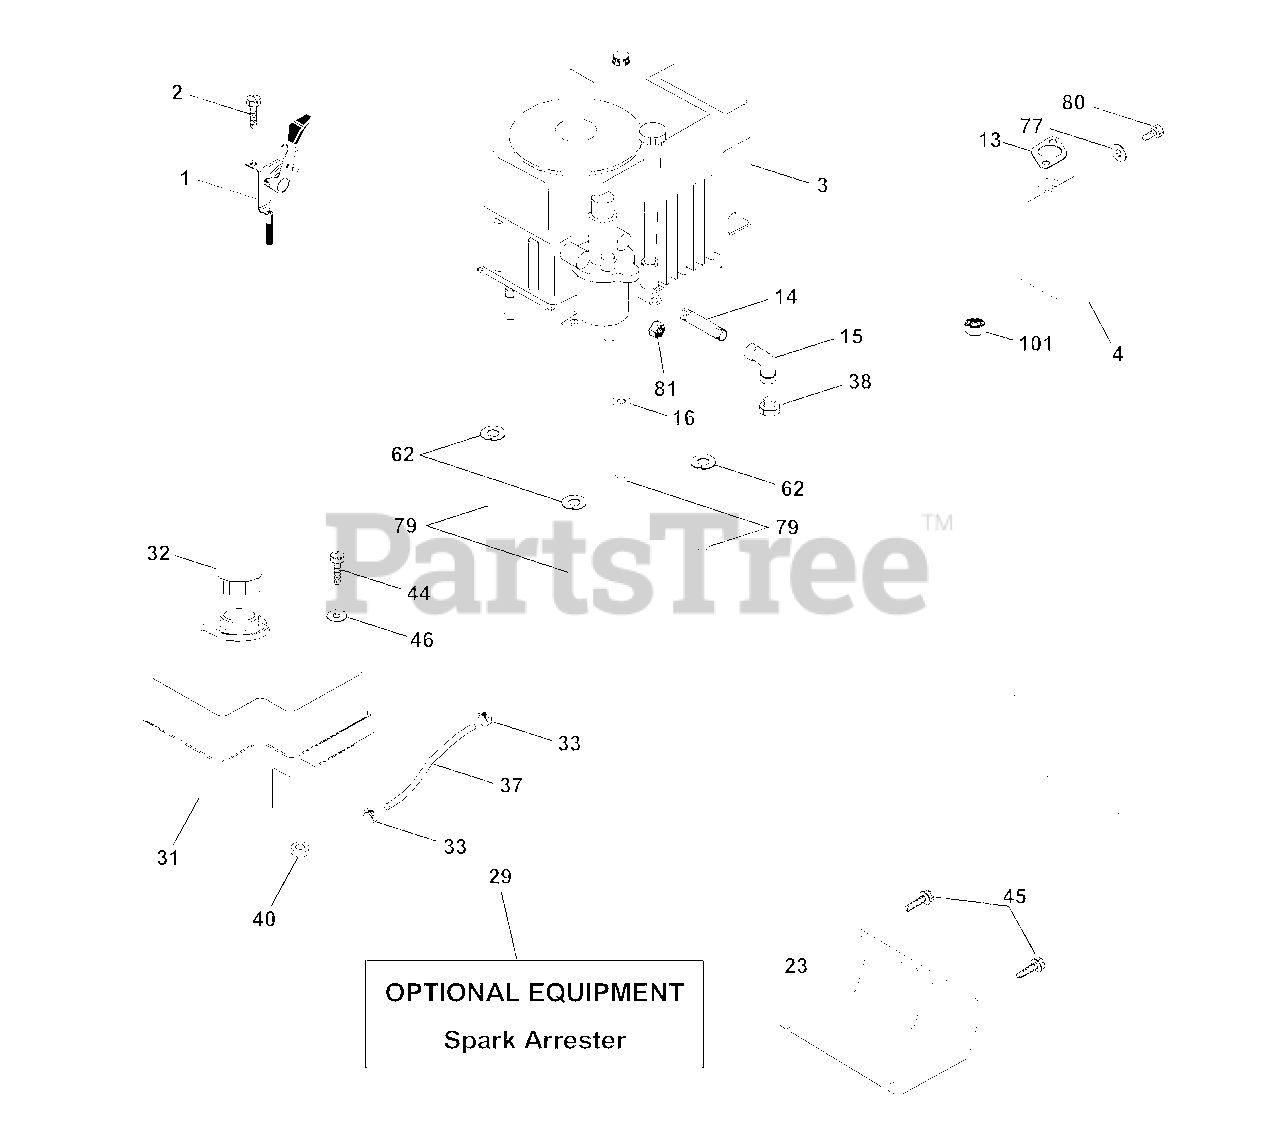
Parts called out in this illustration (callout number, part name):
1	Control Th/ch 27 LH Flag
2	Screw Hex Thd Cut 1/4-20x5/8 T
4	Muffler
14	Nipple Pipe
15	Elbow Std 90 Degree 3/8-18 Npt
16	Washer Lock Ext Tooth 5/16
23	Shield Brn/Dbr Guard
29	Kit Spark Arrestor (Flat Scrn)
31	Tank Fuel Front 2 00
32	Cap Asm Fuel W/sym Vented
33	Clamp Hose Black
35	Screw
37	Line Fuel 20"
38	Plug Oil Drain
40	Bushing Snap Nyl Blk Fuel Line
44	Screw Hexwsh Thdrol 1/4-20x3/4
46	Washer 9/32 X 7/8 X 16 Ga
62	Washer Lock Hvy Hlcl Spr 5/16
77	Washer 5/16 x 3/4 x 16 Ga.
80	Bolt Hex Hd 5/16-18 x 1/2
81	Nut Flange 1/4-20 Starter Nut
101	Nut Flange M8-1.25
